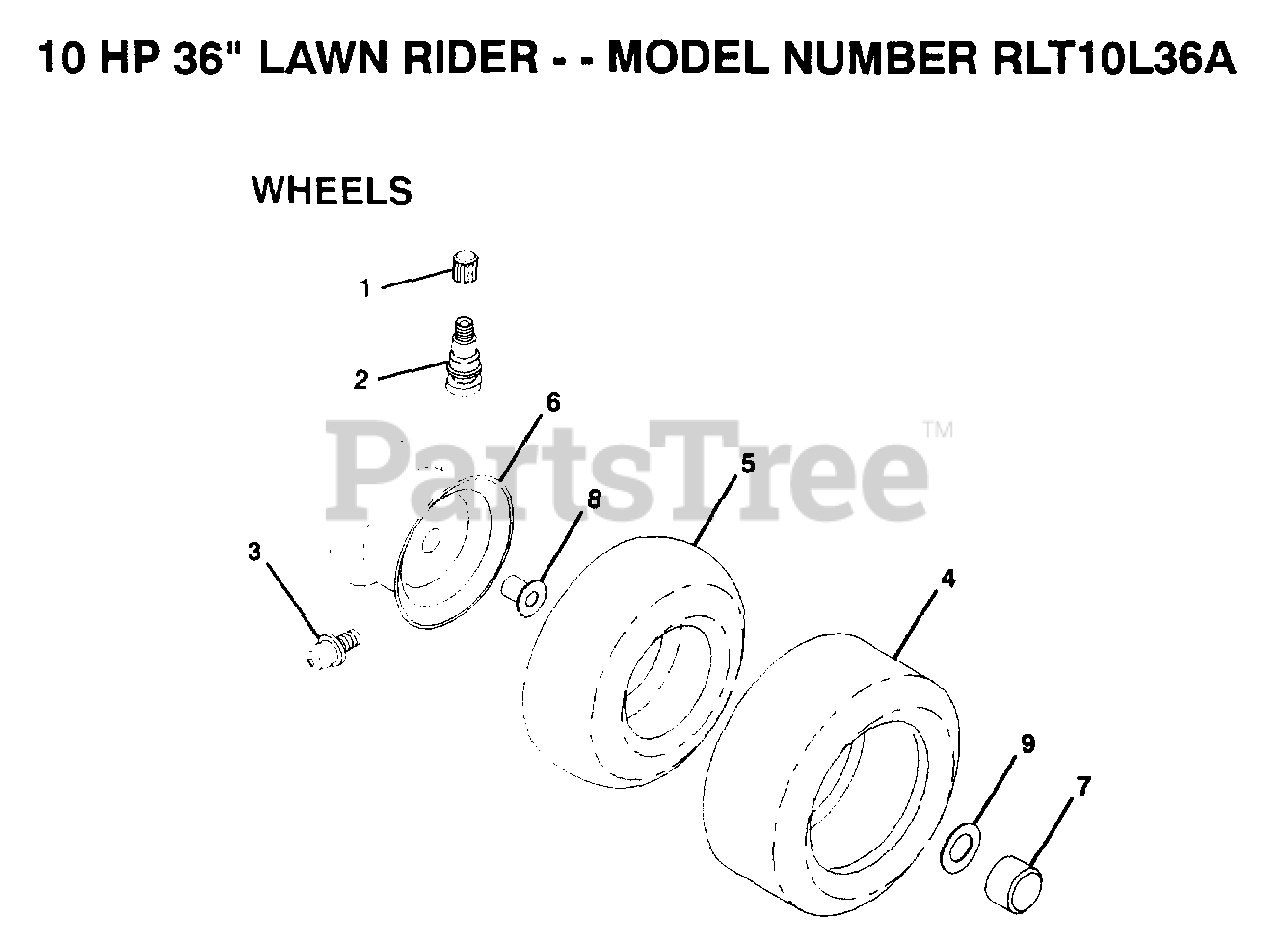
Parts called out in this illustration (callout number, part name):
1	VALVE CAP
2	VALVE STEM LT
3	FITTING LT
5	TUBE.5.3/4.5/6
7	HUB CAP
8	"FLANGE, BEARING"
9	WASHER
